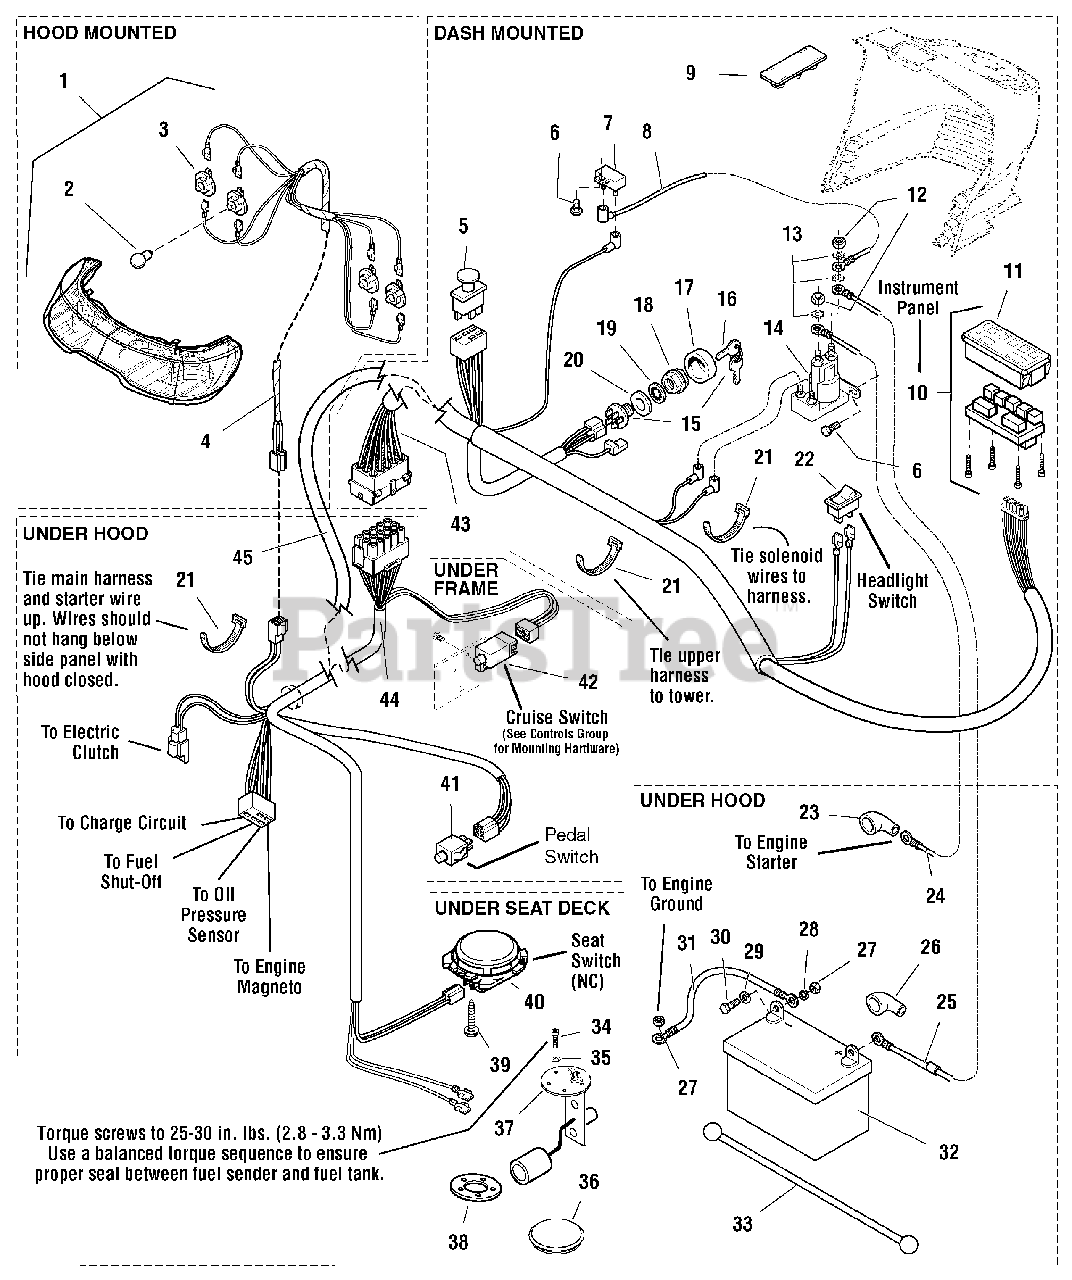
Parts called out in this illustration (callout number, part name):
1	HEADLIGHT ASSEMBLY, 4 Bulb, (Includes Ref. Nos. 2 & 3)
2	BULB, Headlight, 12.8V
3	SOCKET ASSEMBLY, Headlight, Sealed
4	HARNESS, Headlight
5	SWITCH, PTO Push/Pull Symbols
6	CAPSCREW, Hex Washer Head Taptite, 1/4-20 x 1/2, Black
7	BREAKER, Circuit, 12 Volt 20 Amps
8	WIRE, 12GA 5-15/16 Long, Red
9	PLUG, Hole, Square
10	PANEL, Instrument w/ Fuel Gage & Hour Meter (Includes Ref. No. 11)
11	COVER, Instrument Panel
12	NUT, Hex, 5/16-24
13	LOCKWASHER, External Tooth, 5/16
15	SWITCH ASSEMBLY, Ignition, 6 Pin INDAK, (Includes Ref. Nos. 16, 17, 18, 19 & 20)
16	KEYS, Set of 2
17	COVER, For Ignition Switch, Plastic
18	NUT, Hex Flange, 5/8-32, Ignition Switch
19	LOCKWASHER, Internal Tooth, 5/8, Thin
20	WASHER, Shim
21	TIE, Strap, 7-5/16 Long
22	SWITCH, Headlights , 2 Terminal
23	BOOT, Insulator Cable Terminal, 1-15/16 Long, Red
24	CABLE, #6 x 25" Long, Ring Terminals
25	CABLE, #6 x 8" Long, Ring Terminals
26	BOOT, Insulator Battery Terminal
27	NUT, Hex, 1/4-20
28	LOCKWASHER, 1/4
29	WASHER, 1/4
30	CAPSCREW, Hex Head, 1/4-20 x 3/4
31	CABLE, #6 x 26 Long, Ring Terminal
32	BATTERY, 12 Volt
33	STRAP, Battery, 14 Long, Rubber
34	SCREW, Truss Head Phillips, #10-32 x 1/2
35	LOCKWASHER, 3/16 #10
36	PLUG, Hole 3", Round
37	SENDER, Fuel Tank
39	CAPSCREW, Hex Washer Head Plastite, 1/4 x 1/2
40	SWITCH, Seat, Grey, NC
41	SWITCH, Push Button, Foot Pedal
42	SWITCH, Cruise Control, Grey, NO
43	HARNESS, Wiring Upper (Models with 2 Piece Harness)
44	HARNESS, Wiring Lower (Models with 2 Piece Harness)
45	HARNESS, Wiring (Models with 1 Piece Harness)
